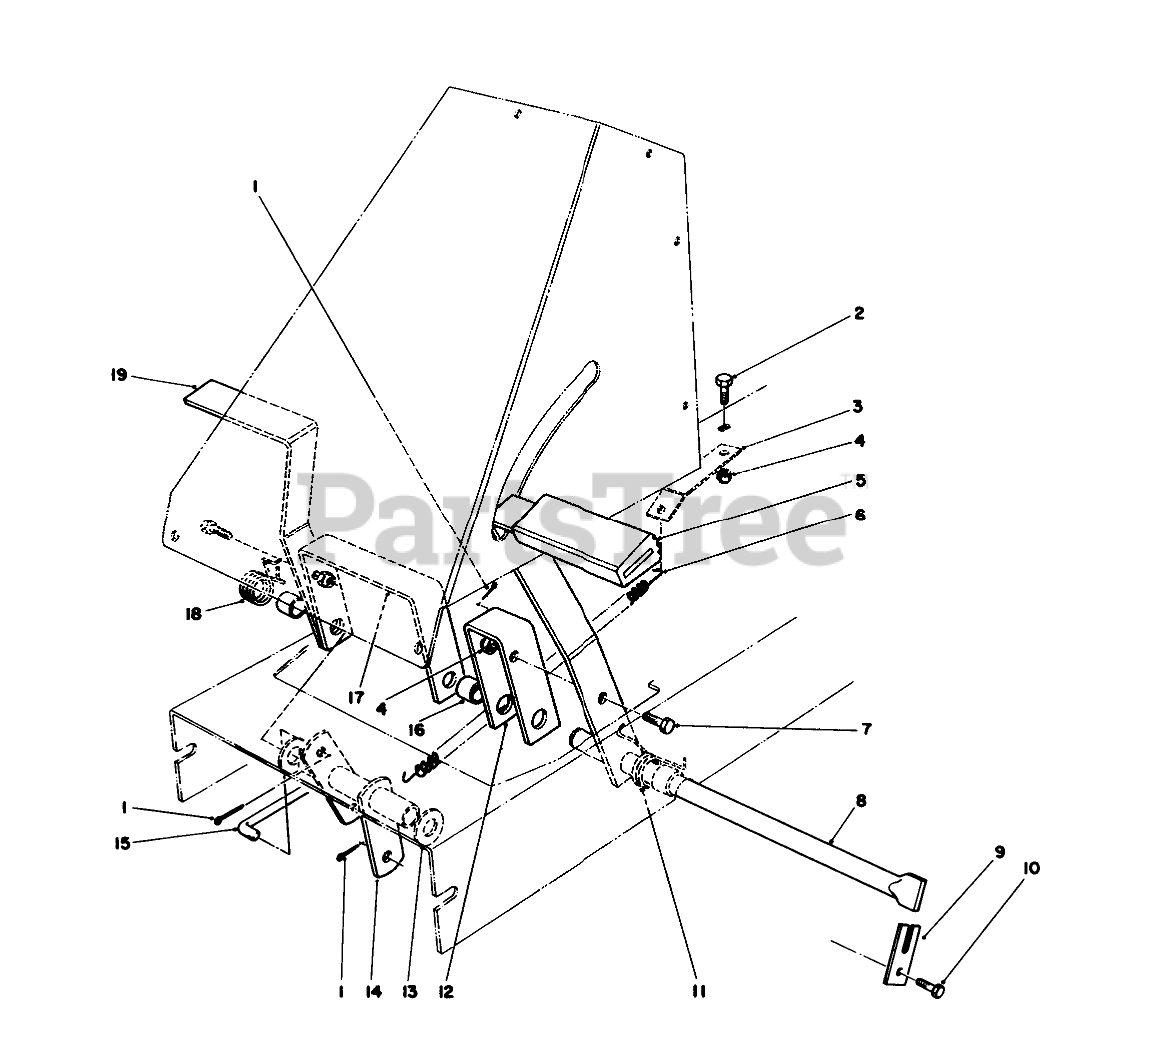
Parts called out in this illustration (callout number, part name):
1	PIN-COTTER
2	SCREW-HH
3	BRKT-SPRING RET
4	NUT-LOCK, NI
5	Pad-Foot Pedal
6	TRACTION SPRING
7	SCREW-HH
8	SHAFT-PEDAL PIVOT
9	RETAINER-SHAFT
10	SCREW-HH
11	SPRING-TORS CLUTCH
12	Bracket-Clutch Pedal
13	WASHER-FLAT
14	Pivot Tube
15	ROD-ENGAGE
16	SPACER-PEDAL
17	Bracket-Brake Pedal
18	SPRING-TORS BRAKE
19	Pedal
